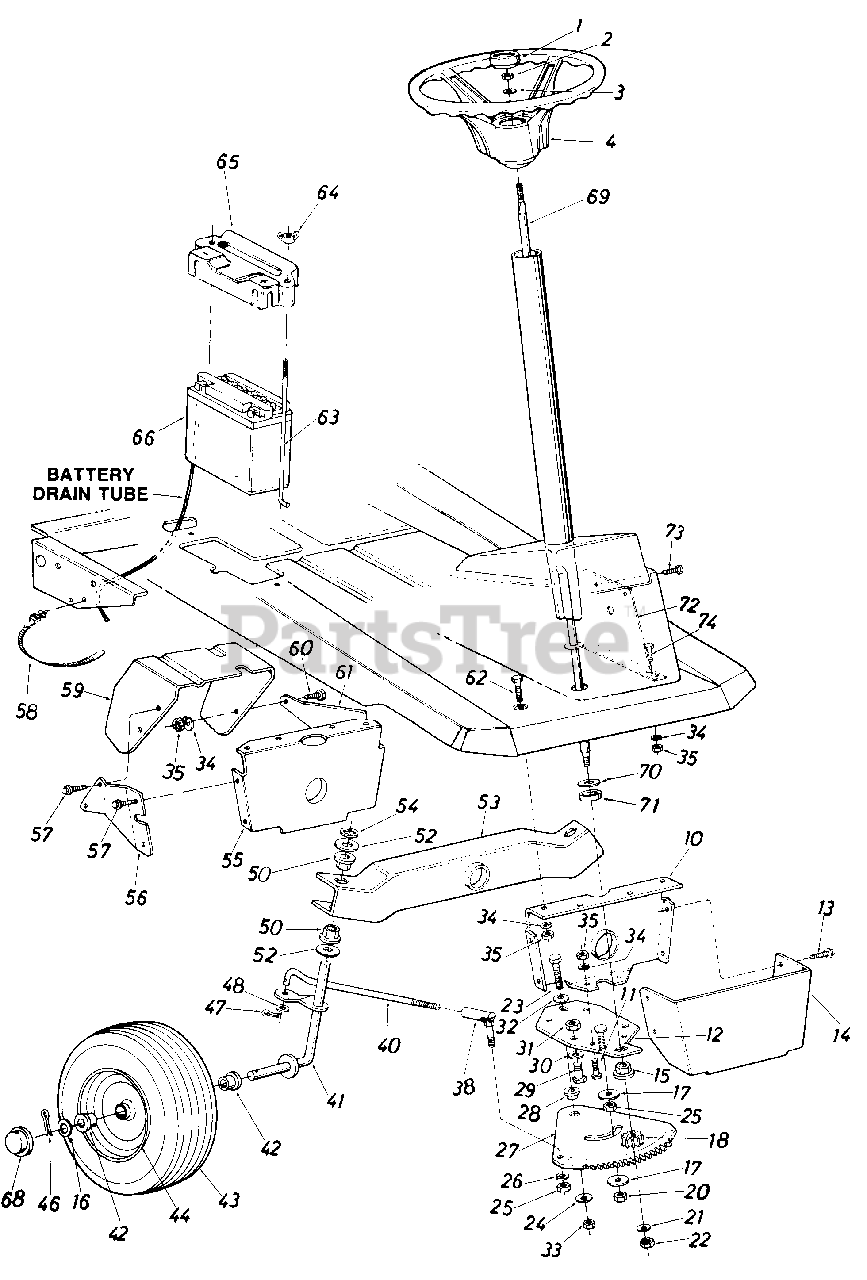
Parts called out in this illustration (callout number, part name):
1	Steering Wheel Cap
2	Hex L-Nut 5/16-24 Thd.
3	Bell-Wash. .345" I.D. x .88" O.D.
4	Steering Wheel Ass'y.
10	Pivot Bar Bracket
11	Hex Bolt 5/16-18 x .75" Lg.*
12	Steering Gear Support Brkt.
13	Hex Wash. Hd. AB-Tap Scr. 1/4 x .62" Lg .
17	Fl-Washer 318" I.D. x 1.37" O.D
18	Steering Pinion Gear
20	Hex L-Nut 3/8-24
21	Fl-Wash. .34" I.D. x .68" O.D.
22	Hex L-Nut 5/16-24 Thd.
23	Hex Bolt 3/8-24 x 1.5 Lg. (Grade 5)
24	Fl-Wash. .385" I.D. x 1.38"
25	Hex Nut 3/8-24 Thd.
26	L-Wash. 318" I.D.
27	Steering Gear Segment
28	Shoulder Spacer .622" Dia. x .218
29	Hex Bolt (Nylon) 1/2-13 x .75"
30	Fl-Wash. .530" I.D. x .930"
31	Hex Nut 1/2-13 Thd.*
32	Bell-Wash. .385" I.D. x .88"
33	Hex Nut 3/8-24 Thd.
34	L-Wash. 5/16" I.D.
35	Hex Nut 5/16-18 Thd.
38	Ball Joint Ass'y. 3/8-24 Thd.
40	Steerinq Tie Rod
41	Front Axle Ass'y.-R. H .
42	Needle Bearing .632" I.D.
43	Front Wheel Ass'y. Comp. (11 x 4.0)
44	Front Wheel Rim Only (11 x 4.0)
46	Cotter Pin 1/8" Dia. x 1.25"
47	Cotter Pin 1/8" Dia. x 1.00"*
48	Fl-Wash. .385" I.D. x .87"
50	Hex Flange Bearing
52	Fl-Wash. .635" I.D. x 1.12"
53	Pivot Bar Ass'y.
54	Speed Nut 5/8" I.D.
55	Pivot Bar Bracket
56	Bracket Reinforcement-R.H.
57	Hex Wash. Hd. AB-Tap Scr. 1/4 x.62" Lg.
58	Cable Tie
59	Clutch-Brake Pedal Ass'y.
60	Hex Bolt 5/16-18 x .75" Lg.
63	Battery Hold Down Rod
64	Wing Nut Solid 1/4-20 Thd.
65	Battery Hold Down Cover
66	12V Battery
68	Hub Cap
69	Steering Shaft Ass'y.
70	Fl-Wash. .635" I.D. x 1.24" O.D.
71	Spacer (Plastic)
74	Hex Bolt 5/16-18 x 2.00" Lg.
